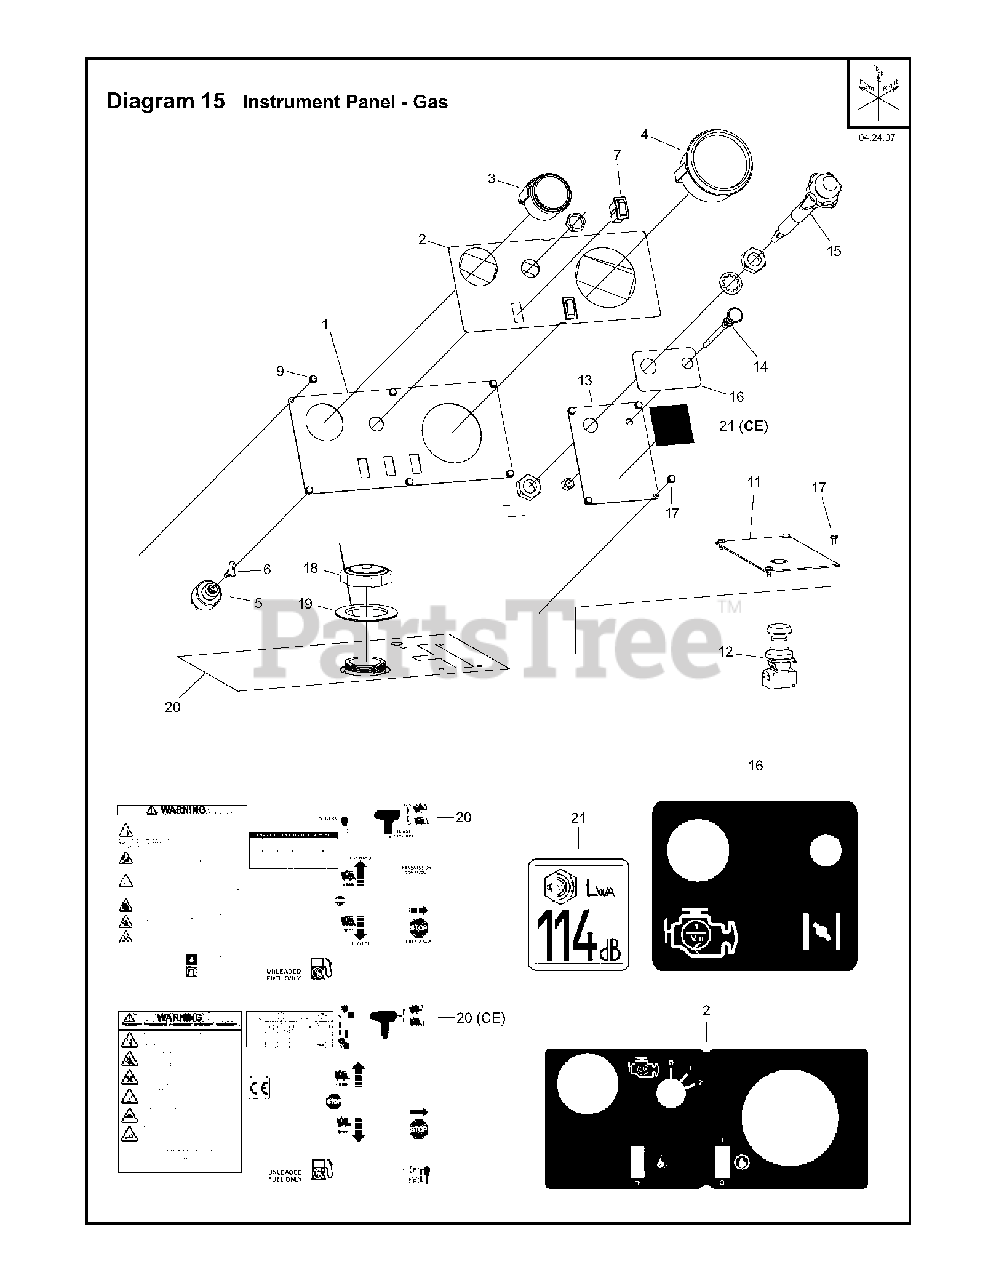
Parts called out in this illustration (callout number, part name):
4	GAUGE. TACH/HOUR METER
5	KEYSWITCH. IGNITION
7	SWITCH. ROCKER SPST
9	HWHSTS. 10-24 x .375 TYPE F SL
12	SWITCH. MUSHROOM STOP
16	DECAL
17	HWHSTS. 10-24 x .375 TYPE F SL
18	GAS CAP w/o GAUGE
